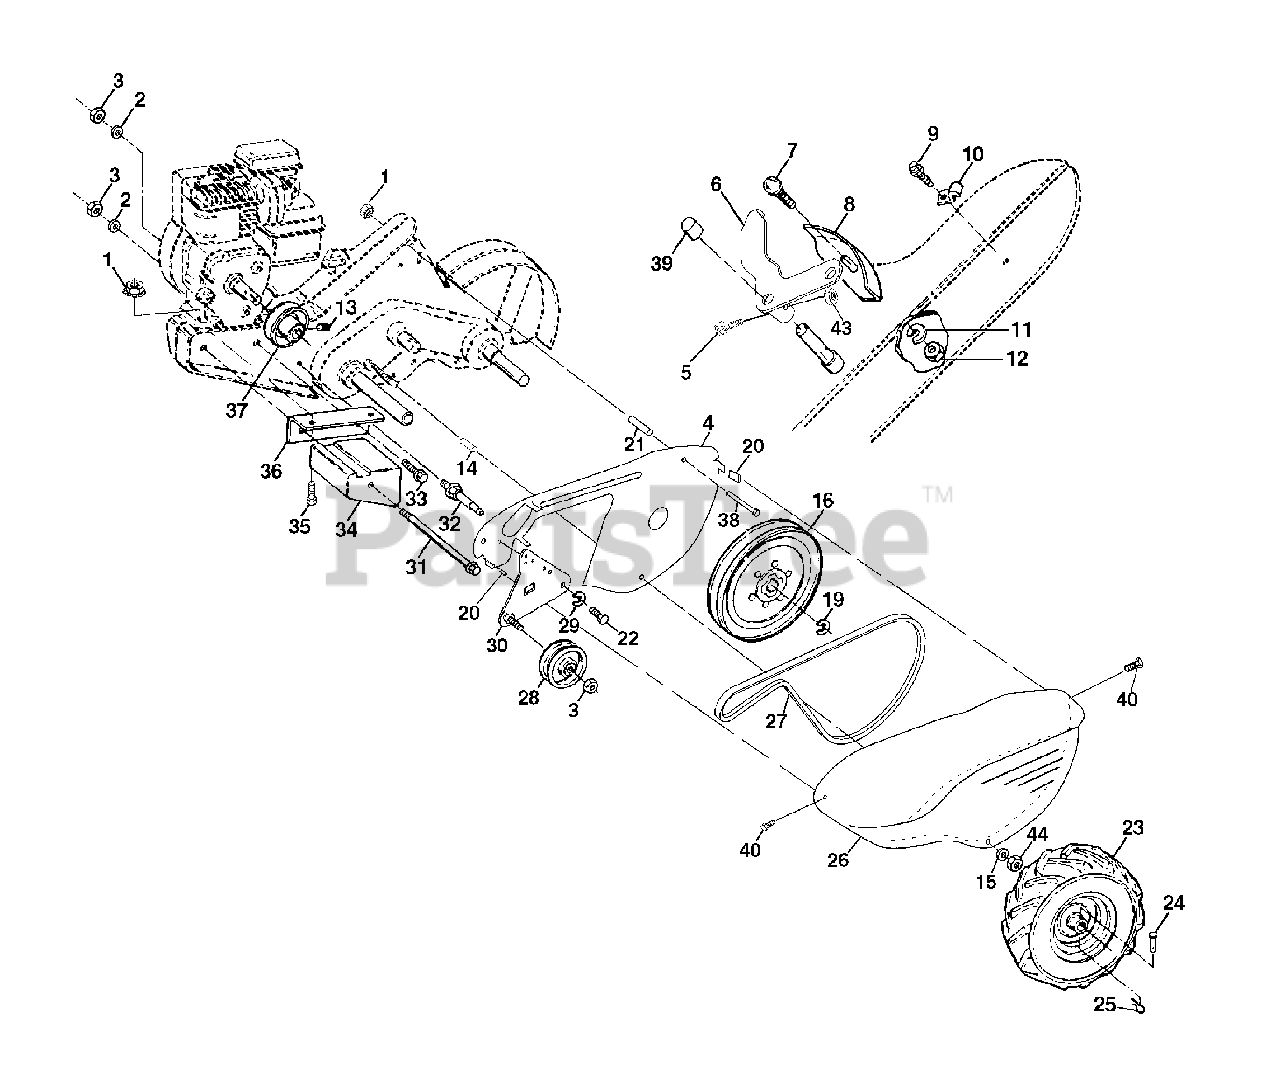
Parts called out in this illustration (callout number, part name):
1	Nut, Keps 5/16-18
2	Washer, Lock 3/8
3	Nut, Hex 3/8-16
4	Shield Inner Belt Guard RT
5	Screw, Shift Lever
6	Lever, Shift
7	Bolt, Carriage 1/4-20 x 1/2 Gr. 5
8	Plate, Shift Indicator
9	Screw, Hex, Washer Head, Slotted #10-24 x 1/2
11	Washer, Lock 1/4
12	Nut, Hex 1/4-20
13	Screw, Set, Hex 5/16-18 x 3/8
14	Spacer, Split 0.327 x 0.42 x 2.09
15	Washer 11/32 x 11/16 x 16 Ga.
16	Sheave, Transmission
19	Retainer, Ring
20	Nut J Clip
21	Spacer, Split 0.327 x 0.42 x 1.220
22	Bolt Fin Hex 5/16-24 Unf x 1/2
23	Rim
23	Tire Valve
24	Rivet, Drilled
25	Clip, Hairpin
26	Guard, Belt
27	Belt, V
28	Pulley, Idler
29	Ring, Klip
30	Bracket, Idler
31	Bolt, Hex 5/16-16 x 12
32	Shaft, Idler Arm
33	Bolt, Hex 3/8-16 x 1
34	Counterweight, L. H.
35	Bolt, Hex 5/16-18 x 1 1/2
36	Bracket, Reinforcement, L. H.
37	Sheave, Engine
38	Bolt Fin Hex 5/16-18 x 2-3/4
39	Cap, Plunger Blk
40	Screw Hex Wsh Hd #8-18 x 1/2
43	Nut, Lock #10-24
44	Nut, Lock 5/16-18
